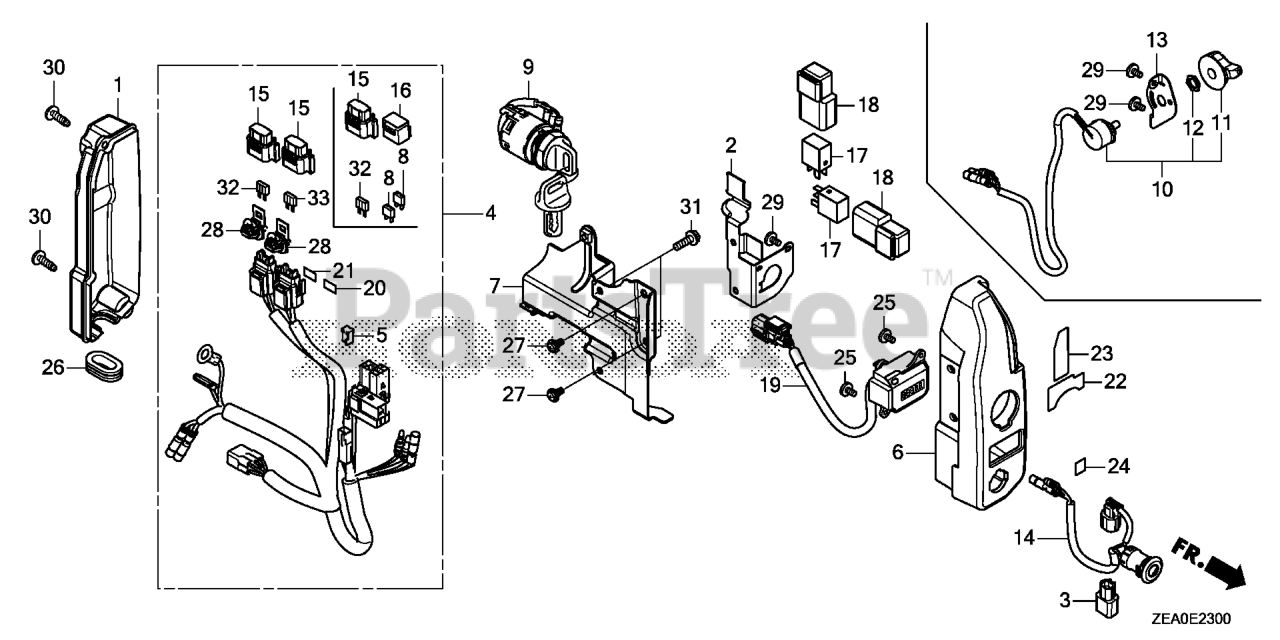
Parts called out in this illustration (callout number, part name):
1	COVER, CONTROL
2	BRACKET, SWITCH BOX
4	SUB-WIRE HARNESS ASSY., ENGINE (17A)
5	CONNECTOR, DIODE (2P) (3A)
6	PANEL, CONTROL
7	BRACKET, CONTROL PANEL
9	SW ASSY., COMB
10	VOLUME ASSY., SPEED
13	BRACKET, SPEED VOLUME
14	LAMP ASSY., INDICATION
15	COVER ASSY., FUSE
17	RELAY, POWER (MICRO ISO 4P) (BLUE)
18	SUSPENSION, POWER RELAY
19	METER ASSY., HOUR
20	LABEL, FUSE (30A)
21	LABEL, FUSE (15A)
22	MARK, ENGINE SWITCH
23	MARK, SPEED VOLUME
24	MARK, FI ALERT
25	SCREW, TAPPING (3X8) (PO)
26	GROMMET, CONTROL BOX
27	SCREW, PAN (5X10.5)
28	CLIP, CONNECTOR (BLACK)
29	SCREW, TAPPING (5X14) (PO)
30	SCREW, TAPPING (5X16) (PO)
31	BOLT, FLANGE (6X20)
32	FUSE, MINI (15A)
33	FUSE, MINI (30A)
